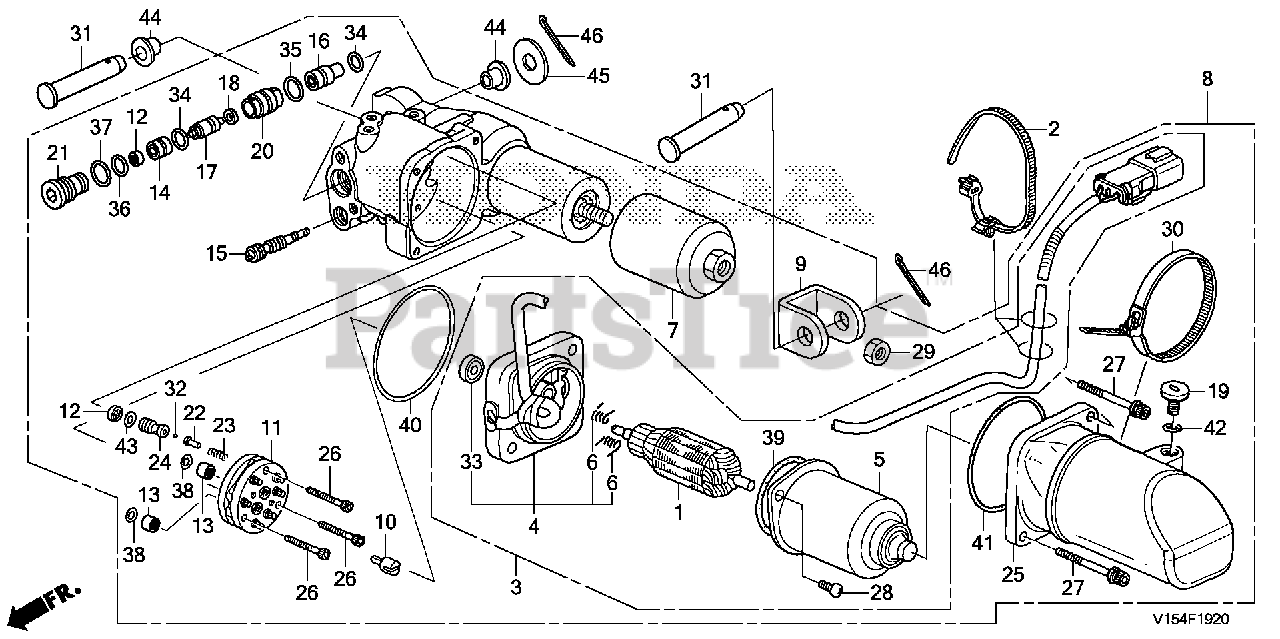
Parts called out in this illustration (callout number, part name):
2	BAND, WIRE HARNESS
3	MOTOR ASSY., POWER ROLLING
4	BRACKET ASSY.
6	SPRING, MOTOR
7	COVER, DUST END
8	ROLLING ASSY., POWER
9	JOINT, METAL
10	JOINT, DRIVE
15	VALVE, MANUAL
17	SPOOL, VALVE
18	RING, BACK-UP
19	BOLT, PLUG
22	GUIDE, SPRING
23	SPRING, VALVE
24	SEAT, VALVE
26	BOLT, SOCKET
27	BOLT, SOCKET
28	SCREW, PAN (5X0.8)
30	BAND, WIRE HARNESS
31	PIN (12X46)
32	BALL, STEEL
34	O-RING (1.5X10.7)
35	O-RING (1.5X13.5)
36	O-RING (1.5X15.5)
37	O-RING (1.8X18.8)
38	O-RING (1.5X8.5)
40	O-RING (2.0X62.5)
41	O-RING (2.4X66.6)
42	O-RING (1.9X9.8)
43	O-RING (1.5X5.5)
44	BUSH, CYLINDER (UPPER)
45	WASHER, PLAIN (12MM)
46	PIN, SPLIT (3.0X25)
46	PIN, SPLIT (3.0X45)
